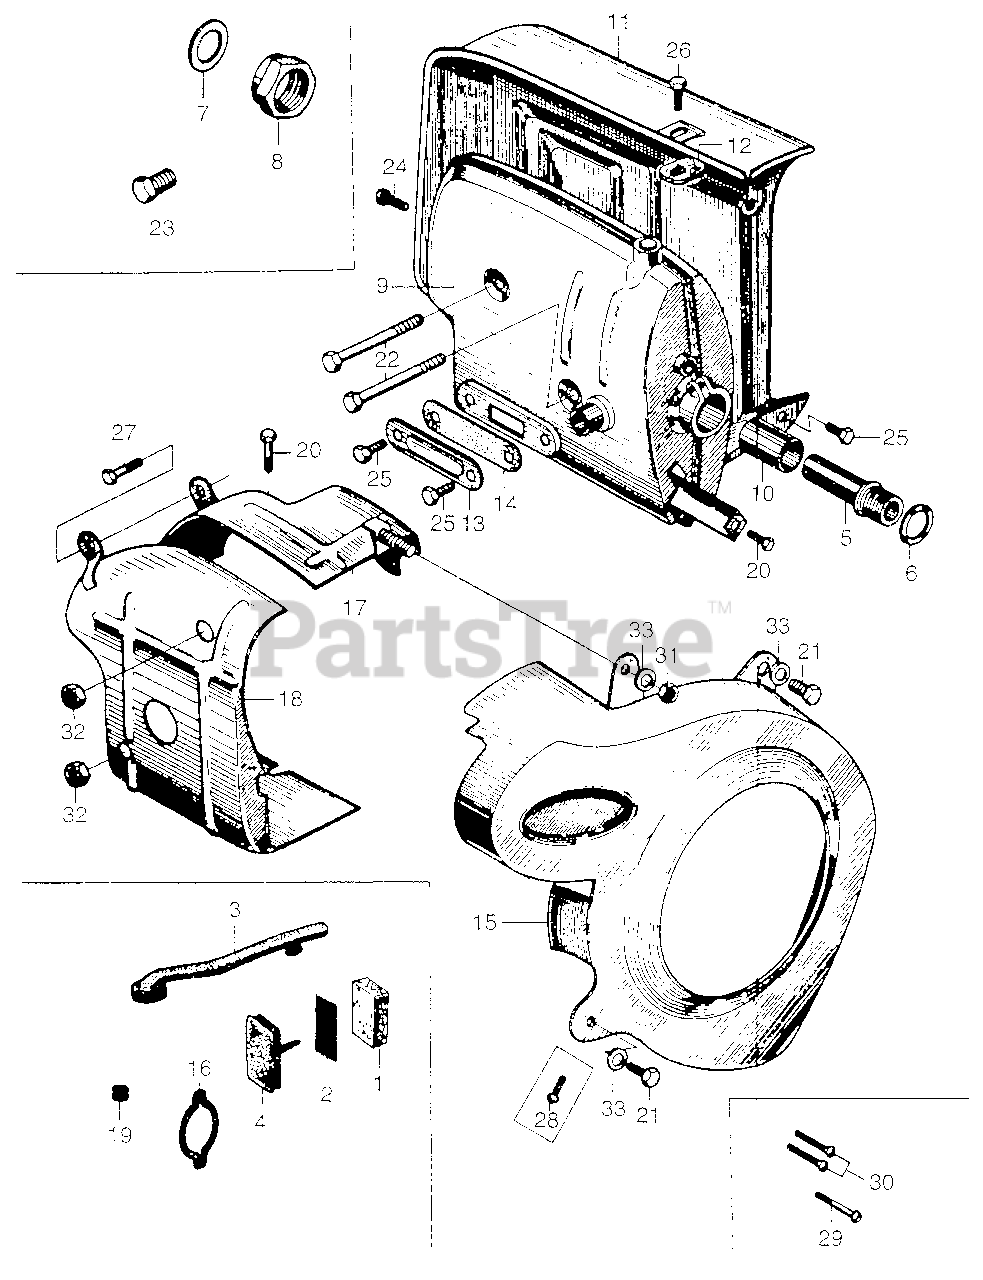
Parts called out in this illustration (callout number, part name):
1	ELEMENT, AIR CLEANER (NOT AVAILABLE)
1	ELEMENT, AIR CLEANER
2	GRID, FILTER (NOT AVAILABLE)
2	GRID, FILTER
3	PIPE, AIR CLEANER
4	COVER, CLEANER ELEMENT
5	PIPE, EX.
5	PIPE, EX. (NOT AVAILABLE)
6	GASKET, EX. PIPE (NOT AVAILABLE)
7	GASKET, MUFFLER (NOT AVAILABLE)
8	NUT, MUFFLER SETTING
9	MUFFLER
10	SEAL, EX. PIPE (NOT AVAILABLE)
11	PROTECTOR, MUFFLER
12	STOPPER, PROTECTOR
13	LID, MUFFLER
14	GASKET, MUFFLER LID (NOT AVAILABLE)
15	COVER, FAN
16	GASKET, CLEANER COVER
16	GASKET, CLEANER (NOT AVAILABLE)
17	VANE A, GUIDE
18	VANE B, GUIDE
19	RUBBER, GUIDE (NOT AVAILABLE)
20	BOLT, HEX. (5X8)
22	BOLT, HEX. (5X55)
22	BOLT, HEX. (5X55) (NOT AVAILABLE)
23	BOLT, HEX. (8X12)
23	BOLT, HEX. (8X12) (NOT AVAILABLE)
23	BOLT, HEX. (5X18)
24	BOLT, HEX. (5X10)
26	BOLT, HEX. (5X10)
28	SCREW, PAN (5X8)
29	SCREW, PAN (5X18)
30	SCREW, FLAT (5X22)
31	NUT, HEX. (5MM)
32	NUT, HEX. (6MM)
